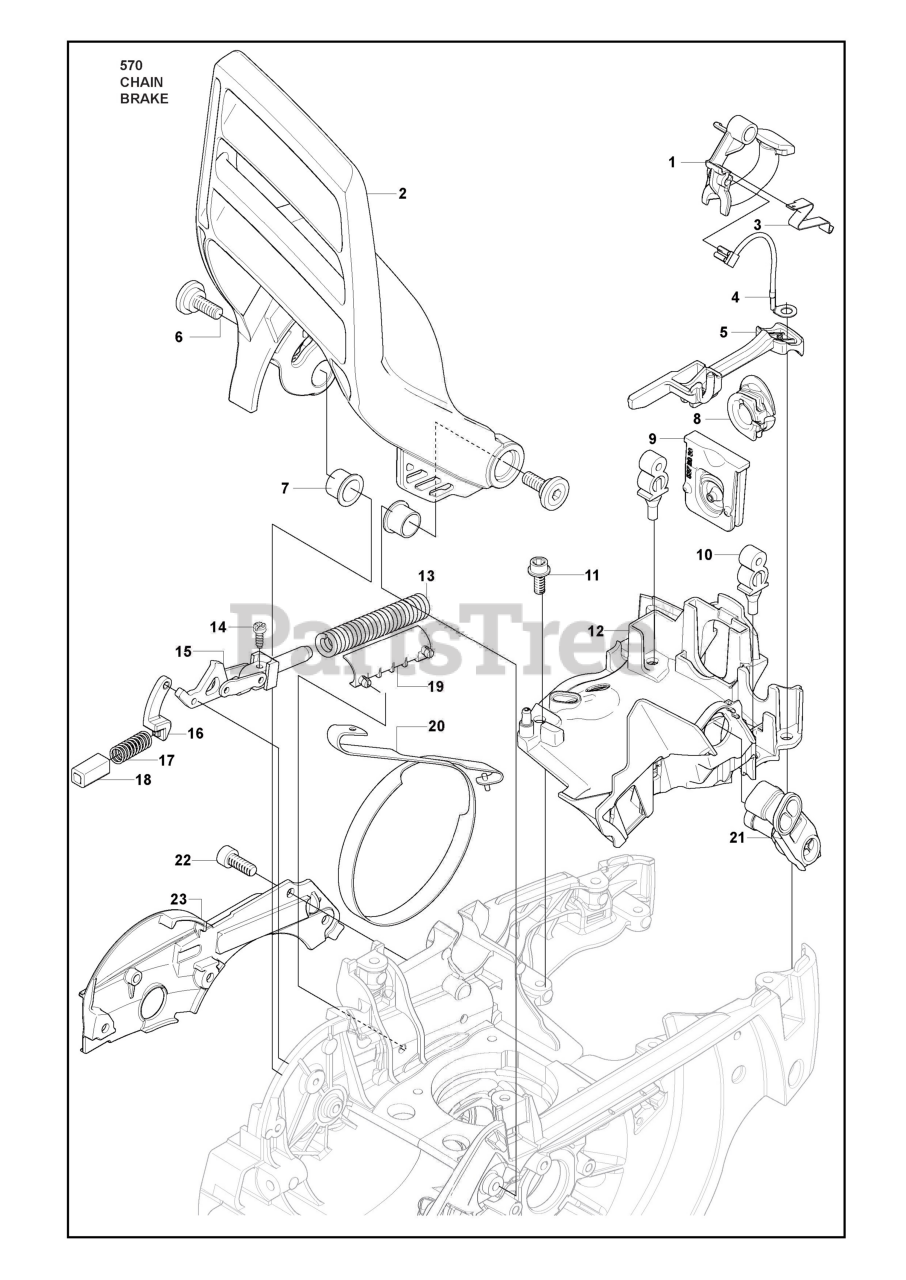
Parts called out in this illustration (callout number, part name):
2	CHAIN BRAKE
5	CHOKE CONTROL
13	BRAKE SPRING
15	KNEE JOINT
17	LOCK SPRING
19	%SUPPORT
20	BRAKE BAND
